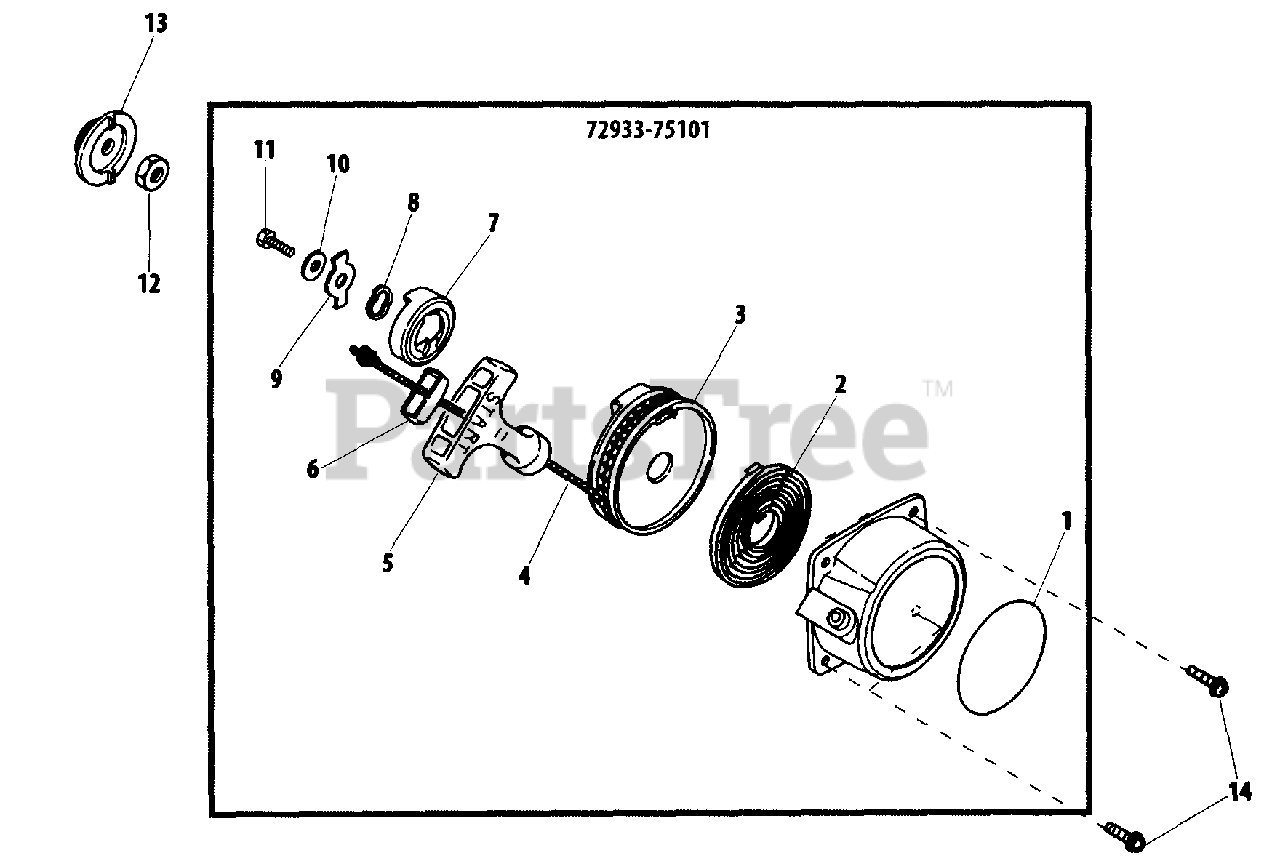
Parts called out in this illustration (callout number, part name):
1	LABEL - IDENTIFICATION
2	SPRING, REWIND
3	REEL, ROPE
4	ROPE, STARTER
5	HANDLE
6	RETAINER, ROPE
7	PAWL, STARTER
8	WASHER - SPRING
9	RETAINER
10	WASHER - 5
11	SCREW - 5
12	NUT - 8
13	PAWL
14	SCREW - 4X12
